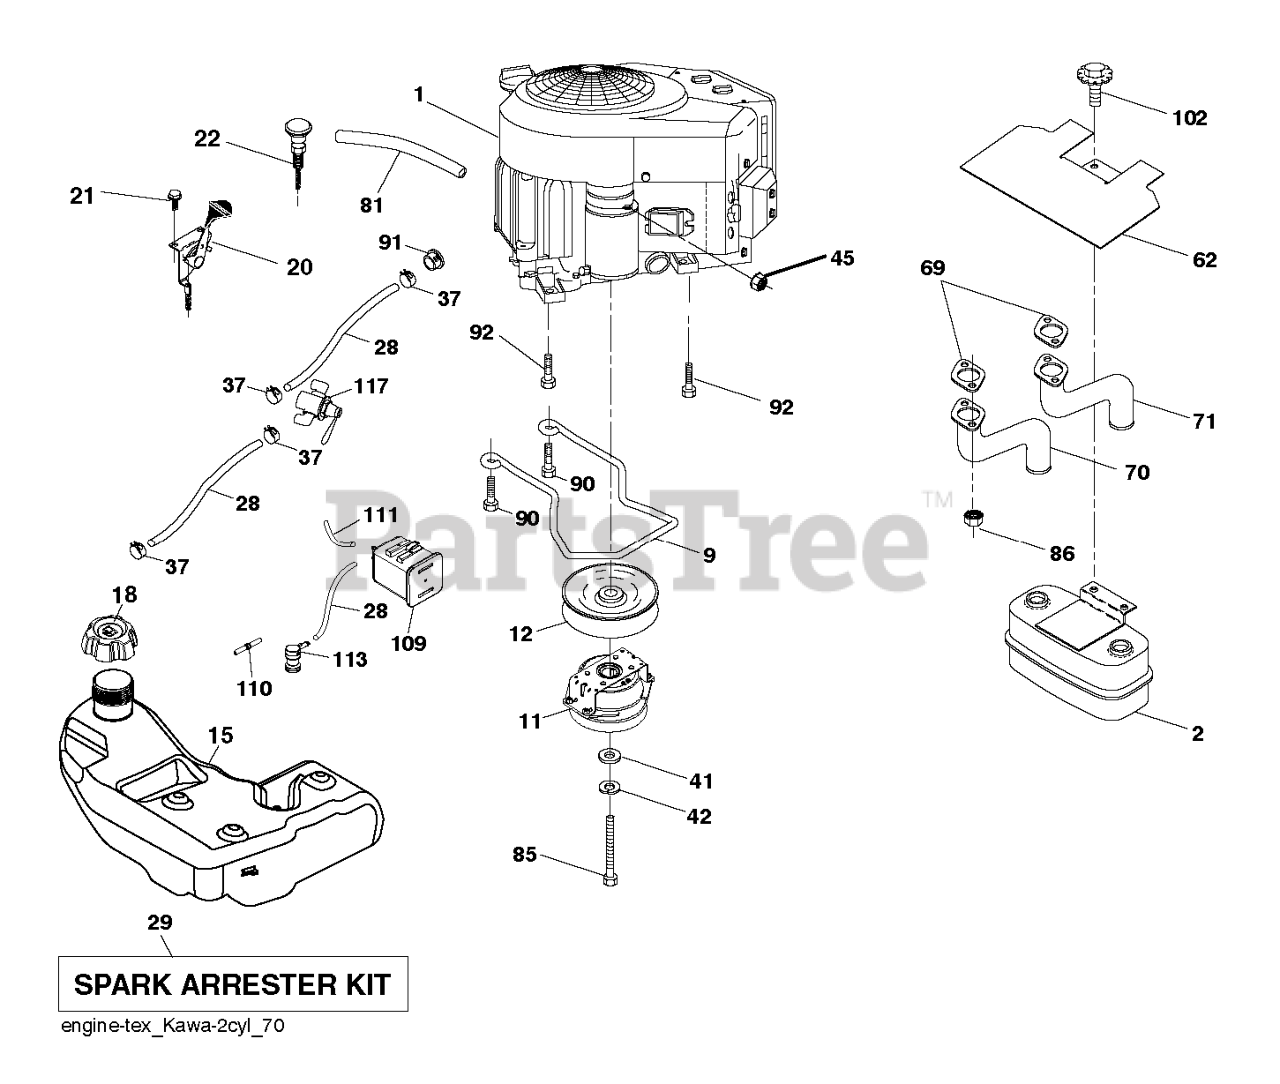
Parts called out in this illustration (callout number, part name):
2	MUFFLER.ASM.TWIN.MNTG.BRACKET
9	KEEPER.BELT.ENG.4.25"2.BLT.431
11	CLUTCH.OGURA.5.0PD.GT1.5A-EH01
12	PULLEY ENGINE
15	TANK.ASM.FUEL.4R.GAL.CARB.17
18	FUEL CAP
18	CAP ASSY FUEL 3" GRAY
20	CONTROL.THROTTLE.COBRA.BLACK
21	SCREW.#10 X 0.750.BOS
22	CONTROL, CHOKE
28	LINE.FUEL.64"REAR.EMIS
29	KIT.SPARK ARRESTOR 794945 B&S
37	HOSE CLAMP
42	WASHER 7/16 LOCK
45	NUT
62	SHIELD.HEAT.MUFFLER
70	TUBE.EXHAUST.LH.FR961/FR730
71	TUBE.EXHAUST.RH.FR961/FR730
81	TUBE, DRAIN OIL ASM.
85	BOLT.HEX.7/16-20X3.GR5.YELLOW
86	NUT.HEX.FLANGE.TOPLOCK
90	SCREW 3/8-16X1
91	BUSHING.1.375OD
92	SCREW 3/8-16X1
102	SCREW
109	CANNISTER, CARBON
110	VALVE.ASM.ANTI-SLOSH
111	RP PURGE LINE
113	VALVE.SLANT.CARTRDG.90 DEG.TEX
117	VALVE FUEL RESERVE
